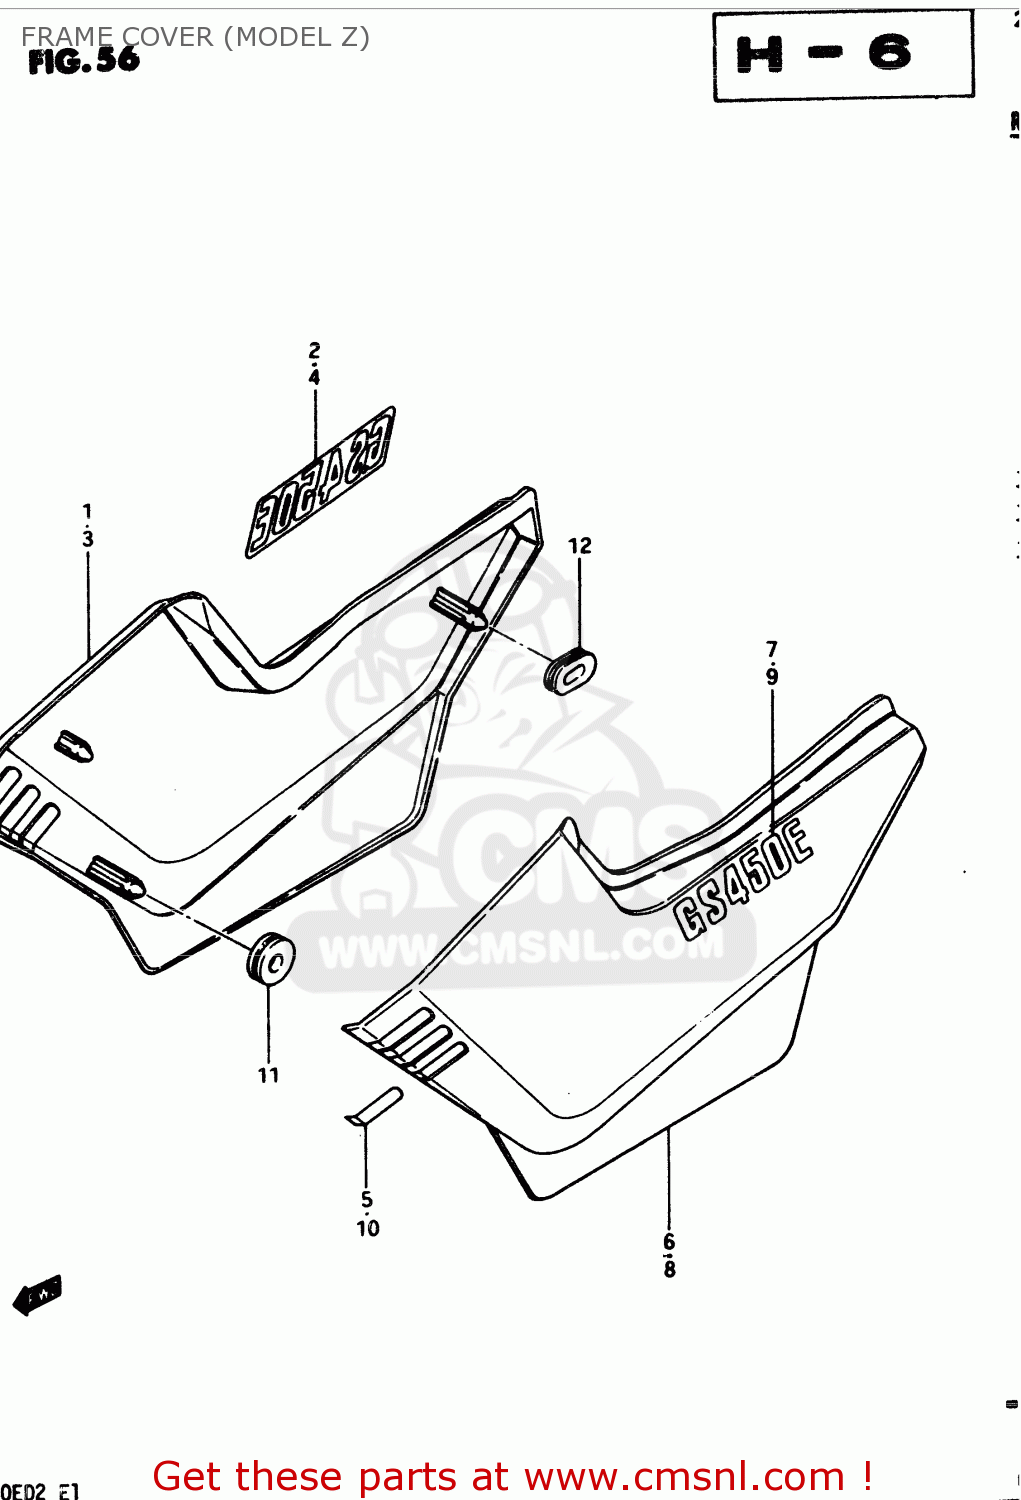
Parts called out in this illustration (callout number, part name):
1	COVER,FRAME,RIGHT
2	EMBLEM,FRAME COVER
3	COVER, FRAME RH (SILVER)
4	EMBLEM, LH
5	LABEL,FRAME COVER DENT
6	COVER,FRAME,LEFT
7	EMBLEM,FRAME COVER
8	COVER, FRAME LH (SILVER)
9	EMBLEM, LH
10	LABEL,FRAME COVER
11	CUSHION
12	CUSHION
